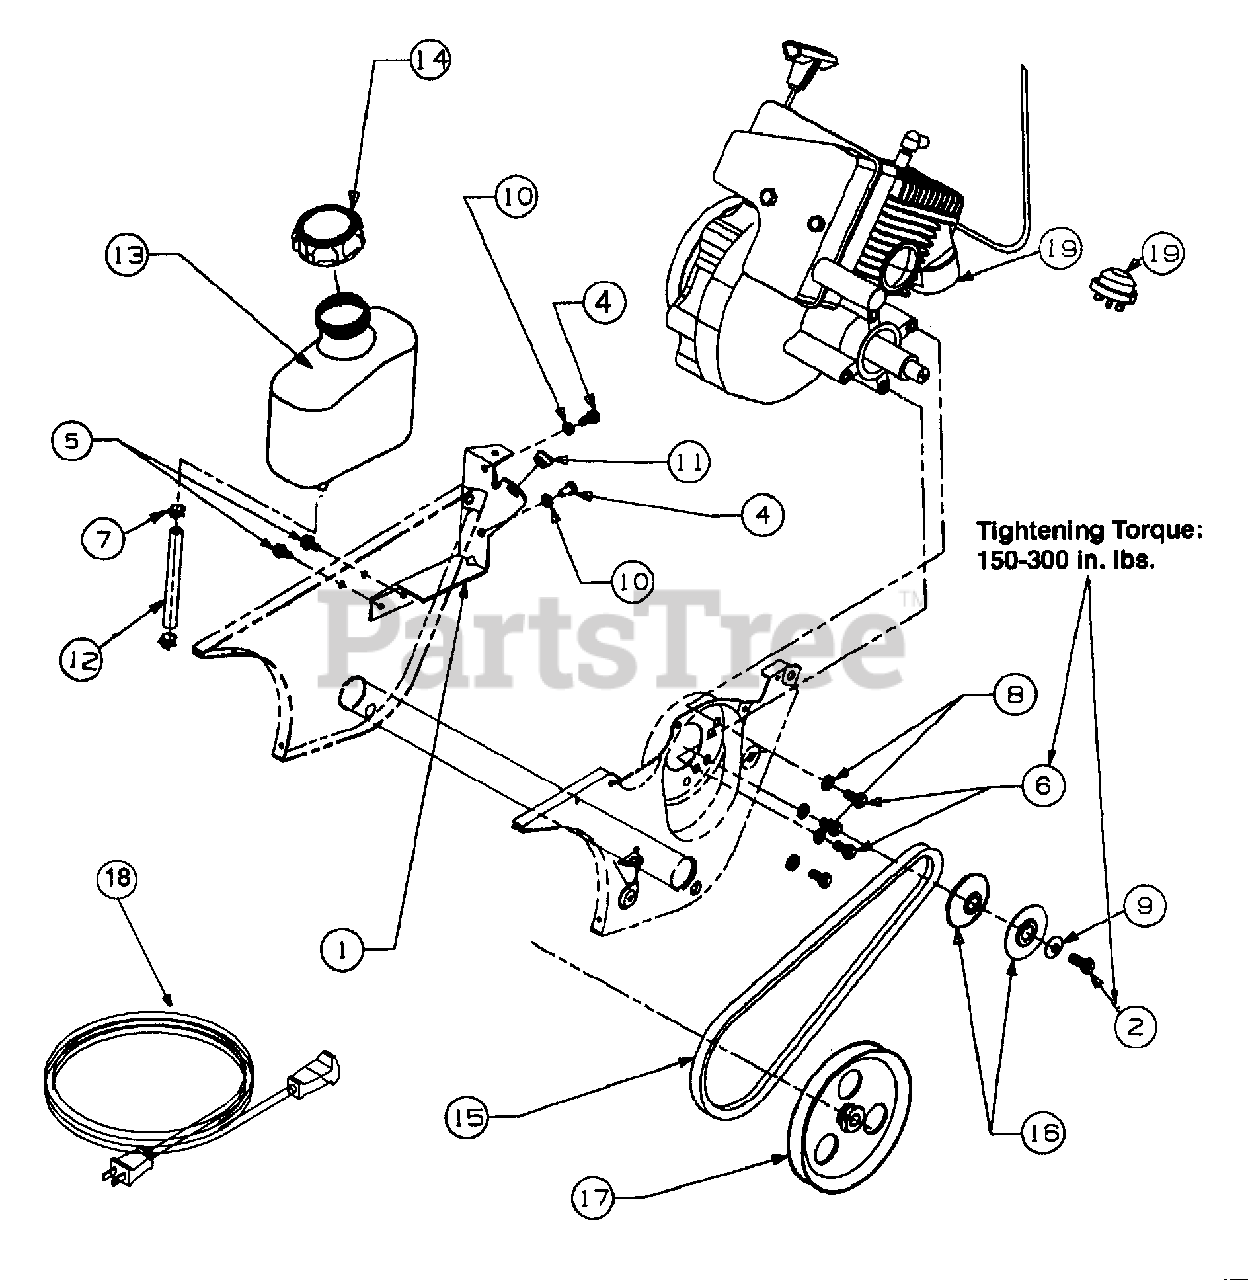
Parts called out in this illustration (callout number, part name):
1	Support Bracket, Gas Tank
2	Hex Cap Screw 5/16-24 x 0.75"
4	Hex Screw 1/4-20 x 0.50"
5	Washer Screw 1/4-14 x 0.625"
6	Hex Cap Screw 5/16-24 x 0.625"
7	Hose Clamp
8	Lock Washer
9	Bell Washer
10	Lock Washer
11	Plastic Bushing
12	Hose, Fuel Line - 16"
13	Fuel Tank - 2 qt.
14	Fuel Cap
15	V-Belt
16	V-Pulley Half
17	V-Pulley Half
18	Cord, Extension
19	Obtain from engine manufacturer
